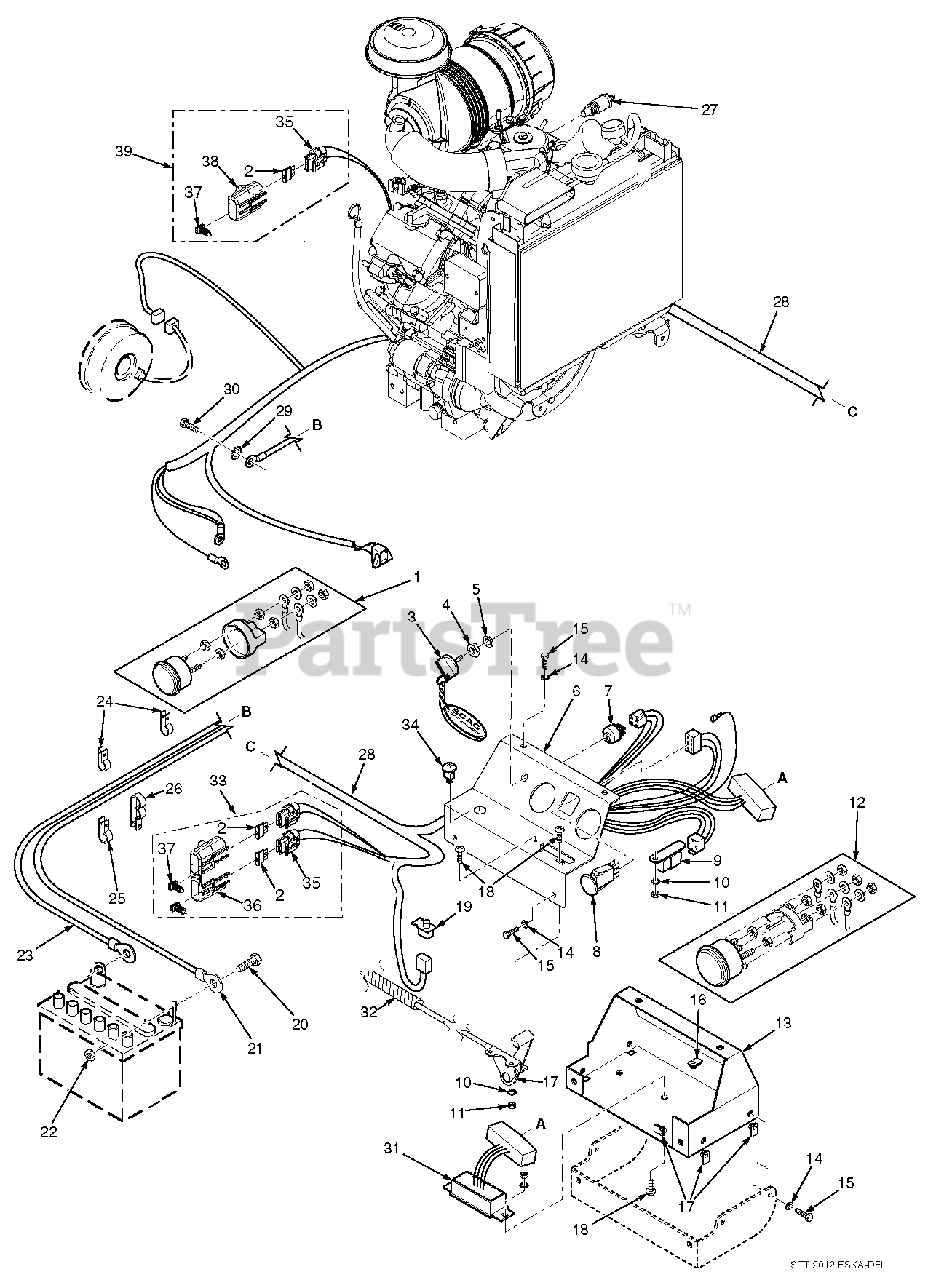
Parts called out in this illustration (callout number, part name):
1	Ammeter
2	Fuse, 20 AMP
3	Key, Ignition
3	Key Assembly w/Fob
4	Nut, Hex 5/8-32
5	Lockwasher, 5/8" Internal
6	Instrument Panel, Top w/Decals
7	Key Switch
8	Switch, PTO
9	Relay
10	Lockwasher, #10 External Tooth
11	Nut, Hex #10-32
12	Water Temp. Gauge
13	Base, Instrument Panel
14	Lockwasher, 1/4"
15	Bolt, Hex Head 1/4-20 x 3/4"
16	U-Nut, 1/4-20
17	Throttle Controls
18	Screw, Phillips Washer Head #10-32 x 1/2"
19	Switch, Interlock-Seat
20	Bolt, Hex Head 1/4-20 x 1/2"
21	Cable, Battery - Red
22	Nut, Hex 1/4-20
23	Cable, Battery - Black
24	Clamp, Cable 1/2" ID.
25	Clamp, Cable 3/4" ID.
26	Clamp, Cable
27	Sending Unit, Water Temp.
28	Wire Harness
29	Lockwasher, 5/16" External Tooth
30	Bolt, Hex Head M8-1.25 x 20mm
31	Electronic Module
32	Heatshield, Flexible
33	Double Fuse Assembly, Sealed
34	Indicator Light, Check Engine
35	Fuse Holder
36	Cover, Sealed Double
37	Clip, Wire
38	Cover, Sealed Single
39	Single Fuse Assembly, Sealed
